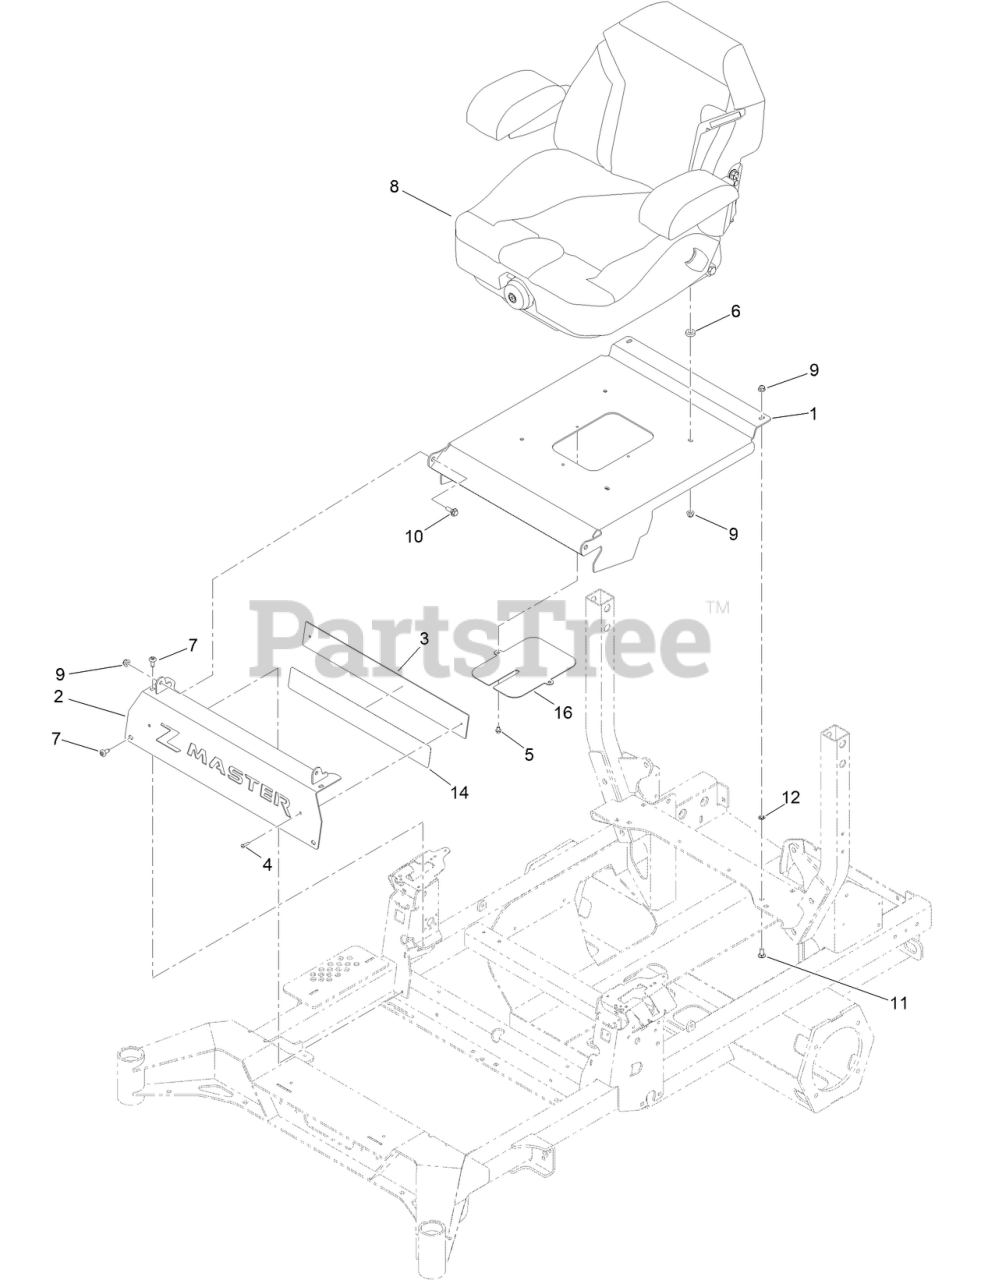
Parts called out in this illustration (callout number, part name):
1	PAN-SEAT
2	BADGE PLATE ASM
3	PLATE-BACKER
4	RIVET-TRIFOLD
5	SCREW-HWH
6	SPACER
8	SUSPENSION SEAT ASM
9	NUT-HF, NI
10	SCREW-SHOULDER
11	SCREW-CARR
12	NUT-PUSH
14	DECAL-BACKER PLATE
16	PLATE-COVER, SEAT
